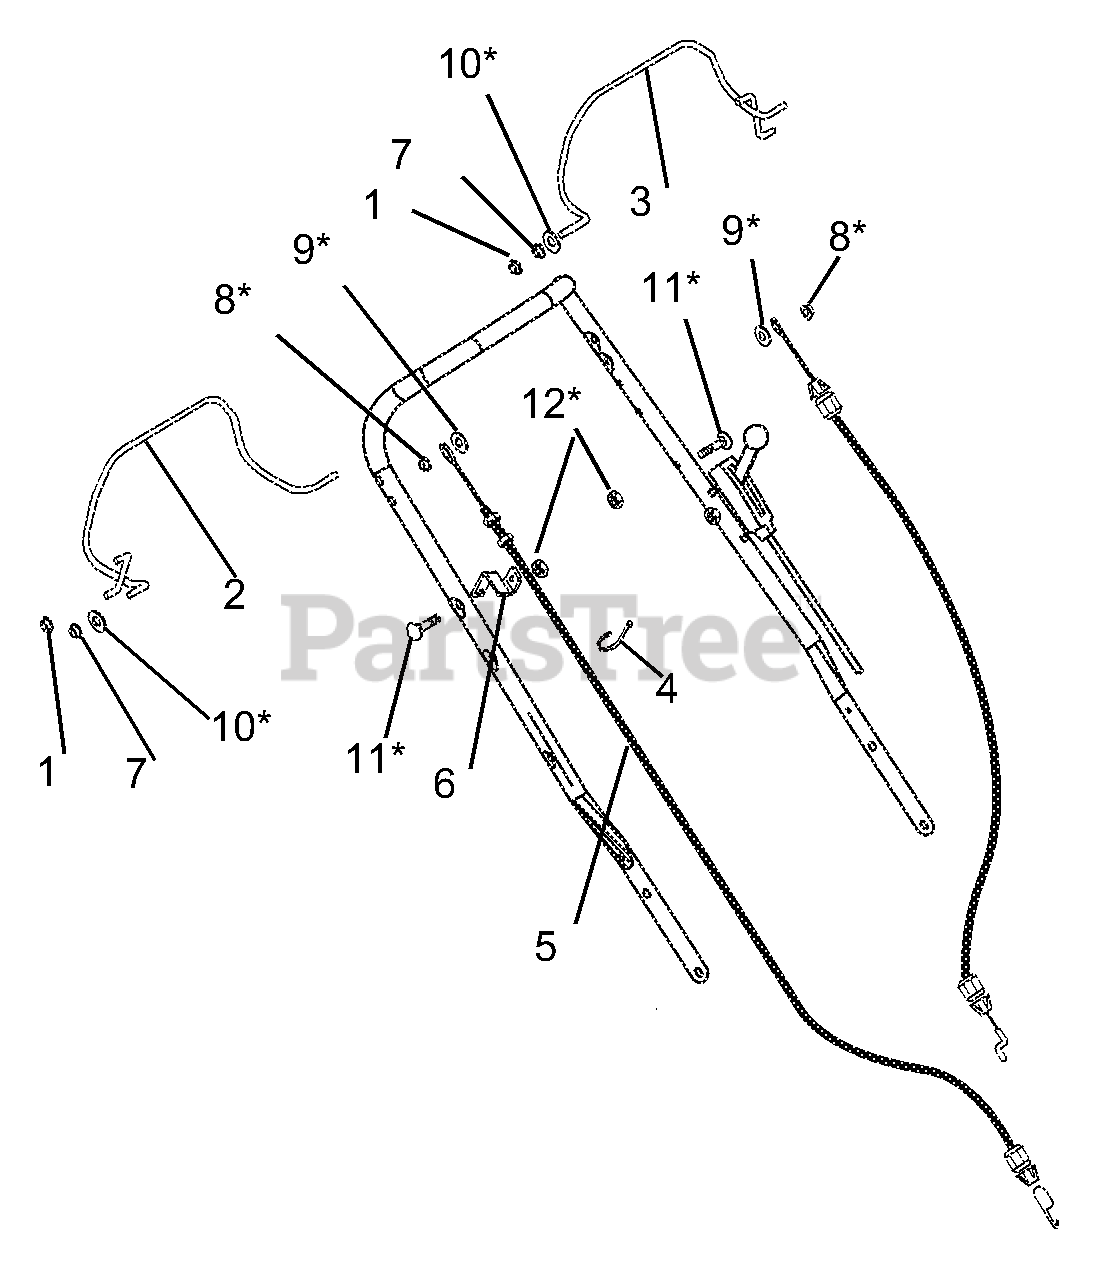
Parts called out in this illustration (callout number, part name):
1	NUT-PUSH .312 DIA. PAL
2	BAIL, TRACTION (WLDMENT)
3	BAIL, ENGINE WELDMENT
4	CABLE TIE LG 5-1/2
5	CABLE, WBLM TRACTION
6	ANCHOR, CABLE
7	BSHG-FLG .325X.444X.440X.560
8	1/4" Push Nut
9	9/32" Washer
10	1/4" Washer
11	1/2" x 1/4" Bolt
12	1/2" Locknut
